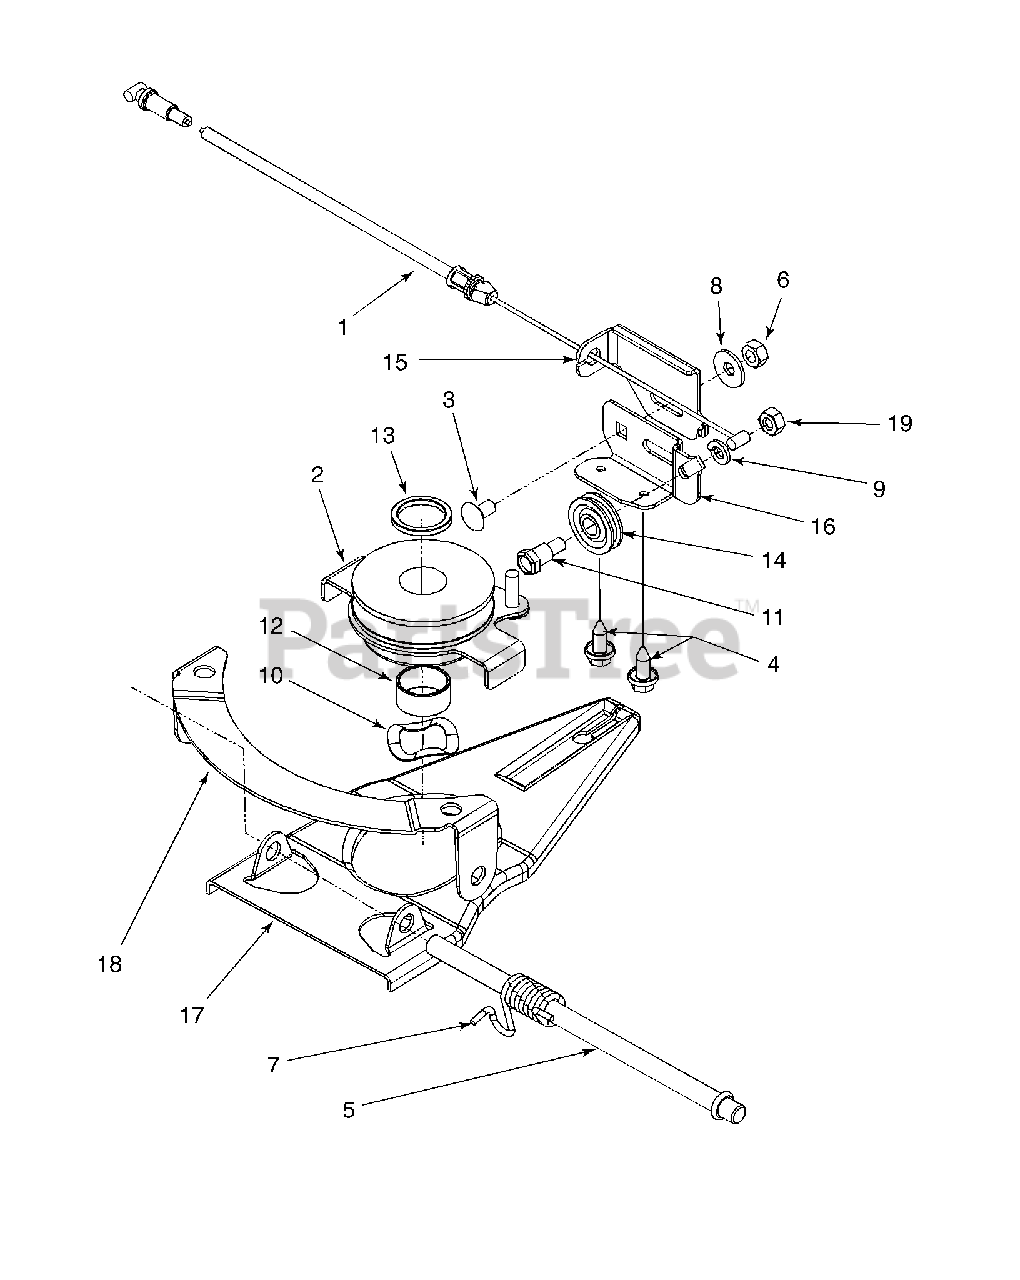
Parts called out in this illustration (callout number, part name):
1	6 Spd. Cable
2	Pulley Ass'y Mult - Spd.
3	Scr. 1/4-20 x .50 Carr.
4	Scr. AB 1/4-14 x .625 Hex hd. Wsh.
5	Pivot Shaft
6	Nut 1/4-20
7	Torsion Spring LH
8	Bell Wash. .265 X .75 X .062
9	Lock Wash. 1/4 Reg Duty
10	Wave Wash. 1.38 x .88 x .029
11	Shld.Scr. .375 x 1/4 -14AB
12	Slev Spcr..88 ID 1.00 OD x.48
13	Slev Spcr .88 ID x 1.13 ID x .12
14	Roller Cable
15	6 Spd. Cable Adj. Bracket
16	6 Spd. Cable Mt. Bracket
19	Hex Nut 1/4-28
